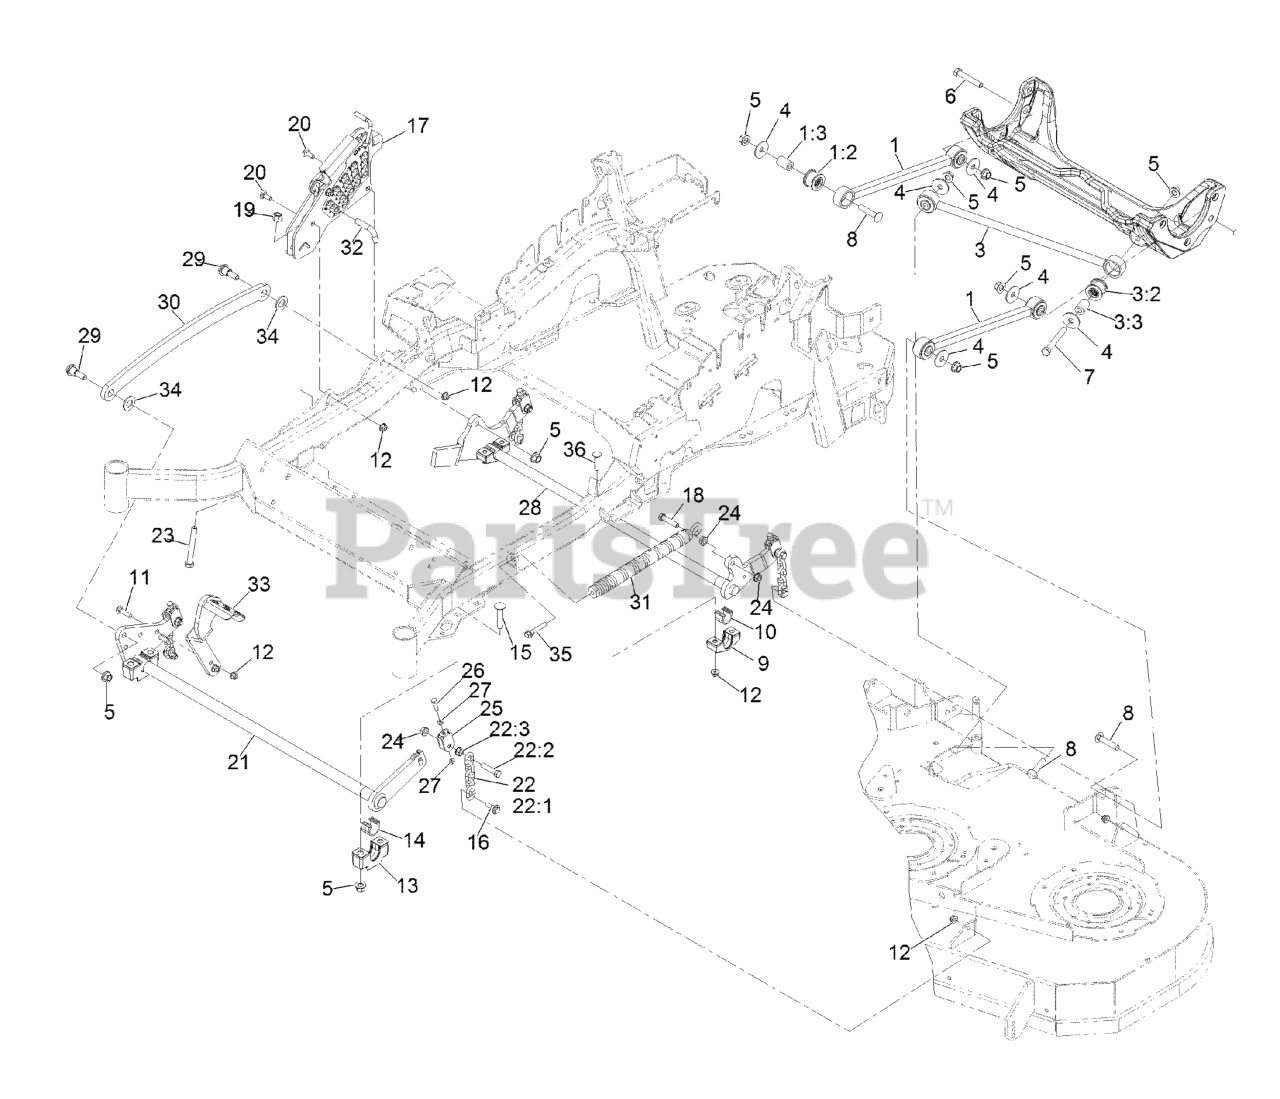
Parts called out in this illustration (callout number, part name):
1	LONG STRUT ASM
1:2	BUSHING-SUSPENSION, RUBBER
3	PANHARD ROD ASM
3:2	BUSHING-SUSPENSION, RUBBER
4	WASHER-THRUST
5	Nut-Lock 1/2-13
6	SCREW-HH
7	SCREW-HH
8	SCREW-CARR
9	SUPPORT-CROSS SHAFT, BEARING REAR
10	BEARING-CROSS SHAFT, REAR
11	SCREW-CARR
12	NUT-HF, NI
13	SUPPORT-CROSS SHAFT, BEARING
14	BEARING-CROSS SHAFT, FRON
15	Bolt-Carriage 1/2-13 X 2 1/2 Spl Neck
16	SCREW-SHOULDER, HHF
17	HOC ASM
18	SCREW-HH
19	NUT-LOCK, NI
20	BOLT-CARR
21	DECKLIFT-FRONT
22	DECK LIFT CHAIN ASM
22:1	CHAIN-LIFT, DECK
22:2	SCREW-HH
23	BOLT-TAP
25	YOKE-ADJUST, DECK
26	SCREW-HH
27	NUT-JAM
28	LIFT-DECK, REAR
29	SCREW-SHOULDER, HHF 1/2-13 X 1.12
30	LINK-LIFT, DECK
31	SPRING-EXTENSION
32	PIN-HOC
33	LEVER-FOOT
34	WASHER-FLAT
35	BOLT-SHOULDER
36	Bolt-Carriage 3/8-16 X 2 1/4
